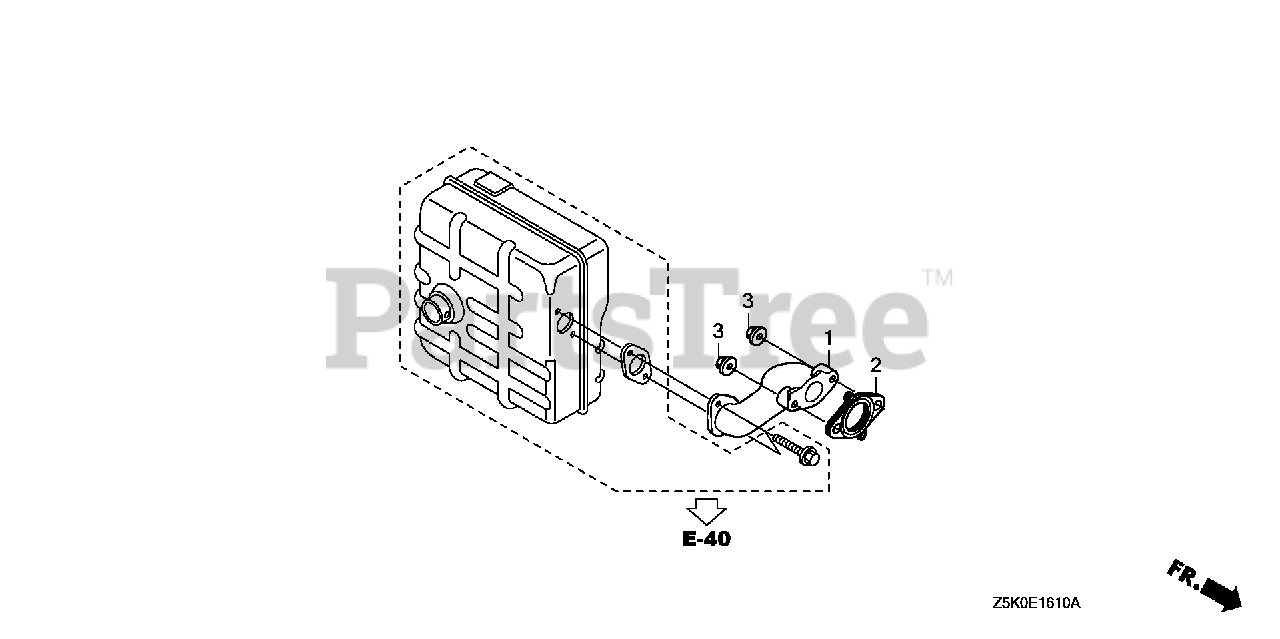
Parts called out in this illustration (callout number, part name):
1	PIPE, EX.
2	GASKET, EX. PIPE
3	NUT, FLANGE (8MM)
